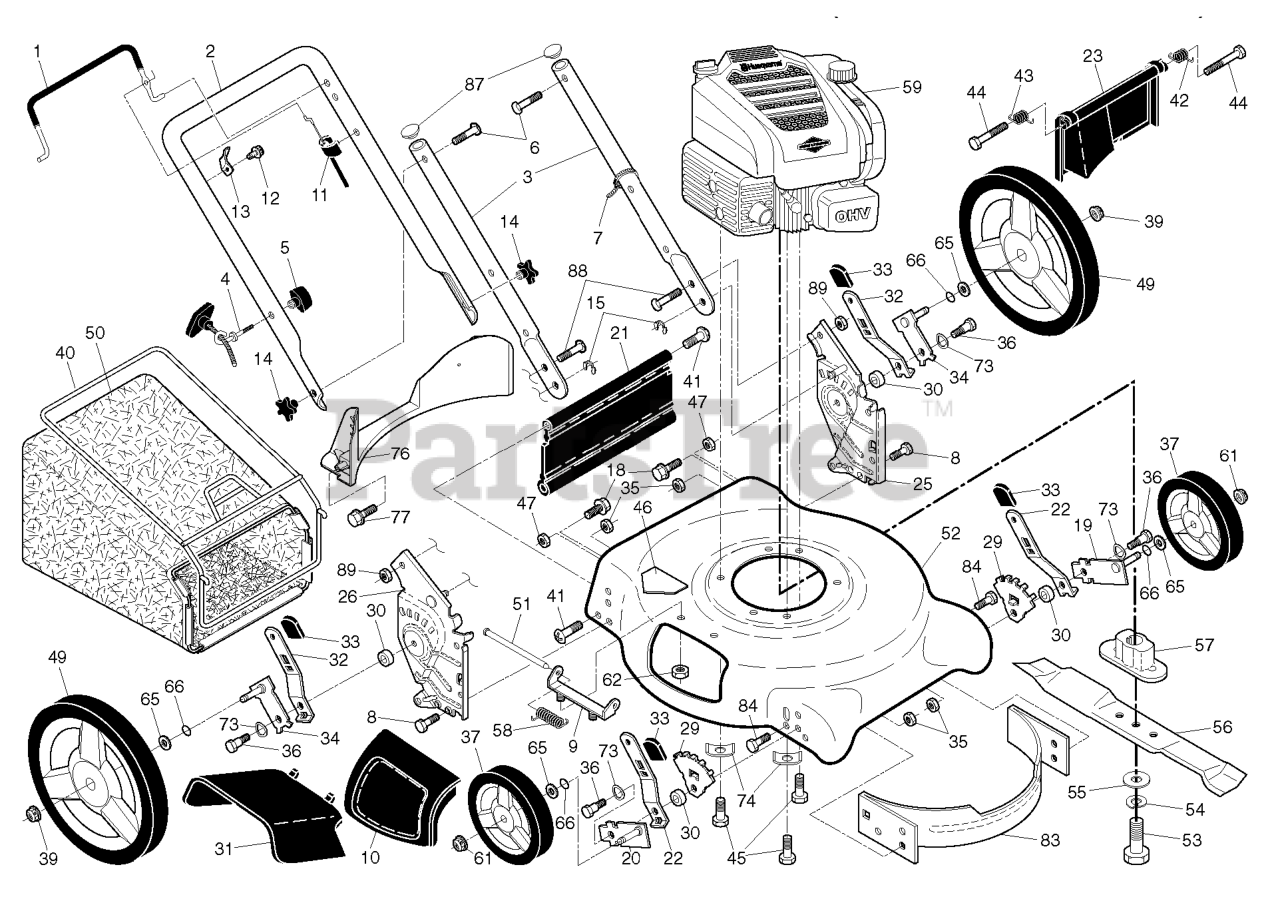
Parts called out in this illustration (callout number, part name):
1	BAIL.ARM.ASSY:STRAIGHT OM
2	HANDLE.UP.DST.SS/VS.FG/RG.NHGY
3	HANDLE.LOWER.DOME.BT.GREY
4	GUIDE.ROPE.BLK.ZINC.CHROM
5	T-KNOB.NEW ROPE GUIDE
6	BOLT, HANDLE 5/16-18X1.75
7	TIE GUIDE
8	BOLT.FIN.HEX.5/16-18X3/4
9	BRACKET.ASM.HOUSING.EZ.MUL
10	DOOR.MULCH.21".REAR.PUSH.GRAY
11	CONTROL.ZONE.ASM
13	BRACKET.UPSTOP.RT
14	KNOB.HANDLE.PLASTIC.STAR.BLACK
15	KLIP RING TI
18	SCREW 1/4X20
19	AXLE ARM ASSY FRONT LH
20	AXLE ARM ASSY FRONT RH
21	SKIRT.REAR.21 DOME
22	SELECTOR SPRING, FRONT
23	DOOR.REAR.21.DOMED.498
25	BRACKET ASM.HAND.HW.21.LT.498
26	BRACKET.ASM.HAND.HW.21.RT.498
29	WHEEL ADJ BRACKET FRONT
30	SPACER.HEIGHT.ADJUSTER
31	DEFLECTOR.CLIPPING.21.GREY
32	SPRING.SEL.22.ECON.HI-WHL.RATO
33	SELECTOR KNOB
34	ARM ASM.AXLE.BZP
35	NUT.FLANGE.HEX.5/16X18.BLACK
36	SHOULDER BOLT 5/16-18
37	WHEEL & TIRES ASSY, FRONT
39	NUT.HEX.FLANGE.3/8-16.LOCKNUT
40	FRAME.BAG.21.REAR.DOMED.PUSH
41	SCREW.1/4-20X21/4.HEX.
42	SPRING.LH.22.REAR.DOOR.EZ.EMPT
43	SPRING.RH.22.REAR.DOOR.EZ.
45	BOLT 3/8-16X1-1/8
46	DECAL.INTERNATIONL.CUTFINGER
47	NUT.LOCK.5/16-18
49	WHEEL.11X1.75.H3SPK.RAD3.BB1
50	GBAG.2323029ER.HU.VENT.GRY.SIL
51	ROD.HINGE.COMBI-C
52	HOUSING.21.M/C.DOME.ORANGE
53	SCREW, HEX HD 3/8-24 X 1-3/8
54	LOCKWASHER
55	WASHER,HARDEN
56	BLADE.21.PUSH/RWGD/FWGD
57	ADAPTOR.BLADE.7/8
58	TORSION SPRING
61	NUT.HEX.FLANGE.3/8-16.LO(3 2)
62	LOCKNUT.NYLOC.1/4-20
65	WASHER.FLAT.1/2
66	O-RING..070X.487.NEOPRENE
73	WASHER.CURVED.CYLINDRICAL
74	WASHER.ENGINE.BZP
76	BAFFLE.REAR.21DOM.REGRND.NATUR
77	SCREW.HX.13X.750
83	BAFFLE.FRONT.21.DOME.US
84	BOLT.5/16HEX.WHS.HD
87	PLUG.PLASTIC.7/8".14-20.GAUGE
88	BOLT.CARRIAGE.LN.5/16-18X.5/8
89	LOCKNUT-FLANGE 5/16-18
